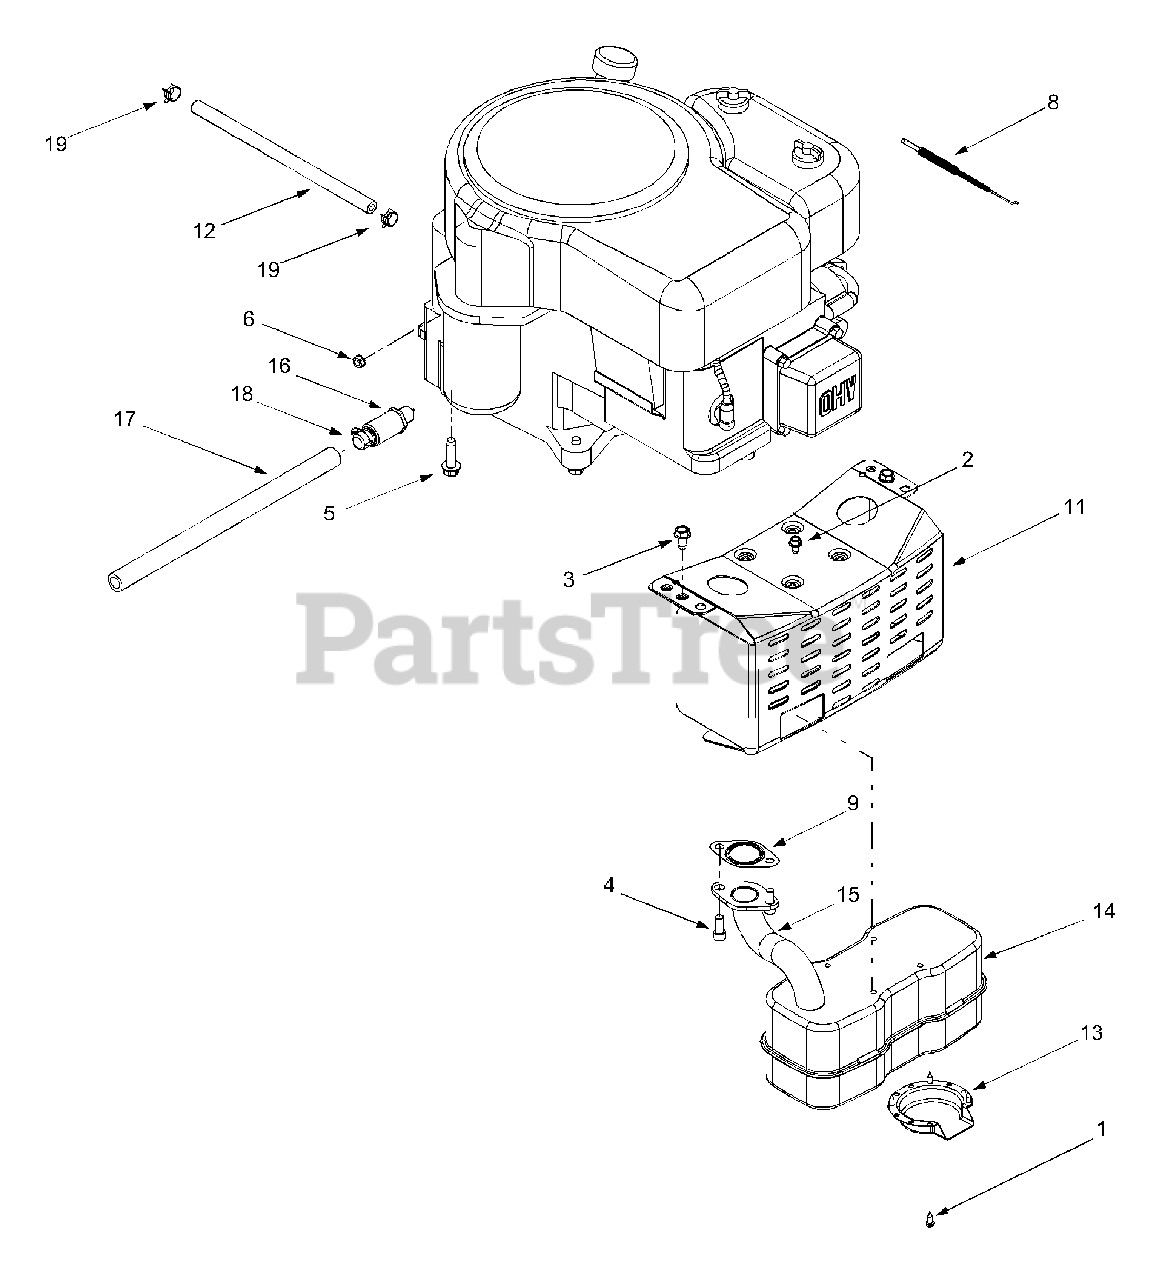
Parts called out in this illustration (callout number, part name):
1	Self-tapping Screw, #8-18 x .50
2	Self-tapping Screw, 1/4-20 x .50
3	Self-tapping Screw, 5/16-12 x .750
4	Socket Cap Screw, 5/16-18 x .75
5	Self-tapping Screw, 3/8-16 x 1.25
6	Hex Sems Nut, 1/4-20
8	Throttle Cable
9	Exhaust Gasket
12	Fuel Line Hose
13	Muffler Deflector
14	Muffler, Single Inlet
15	Exhaust Pipe
16	Oil Drain Valve
17	Oil Drain Hose
18	Oil Drain Cap
